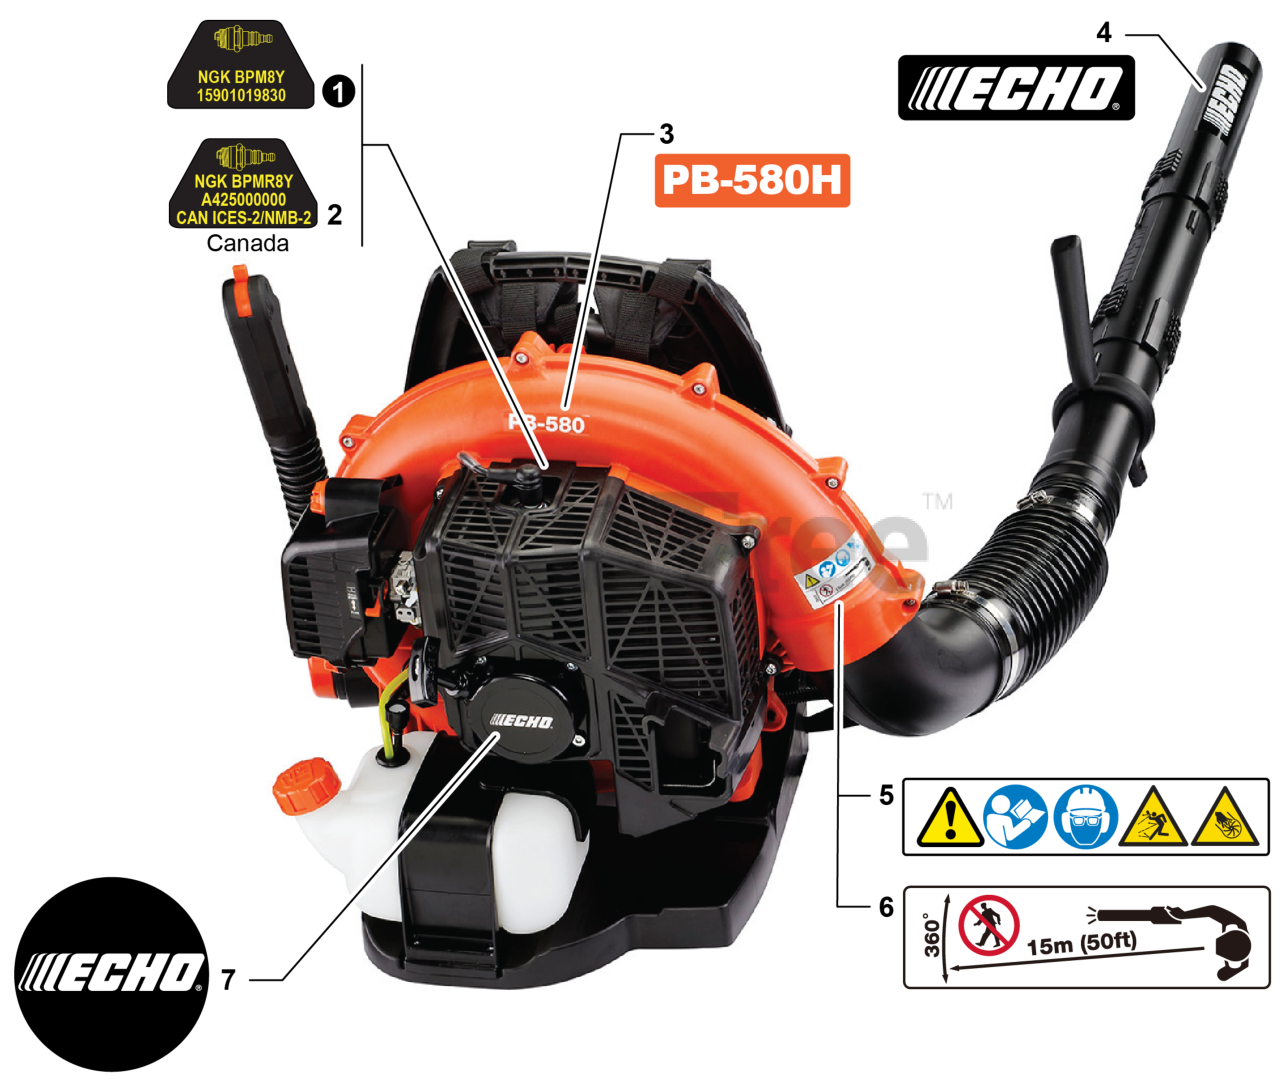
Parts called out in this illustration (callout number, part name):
1	LABEL - SPARK PLUG - BPM8Y
2	LABEL - SPARK PLUG - BPMR8Y
3	LABEL - MODEL - PB-580H
4	LABEL - ECHO
5	LABEL - CAUTION - ISO
6	LABEL - CAUTION - BLOWER
7	LABEL - STARTER - ECHO
